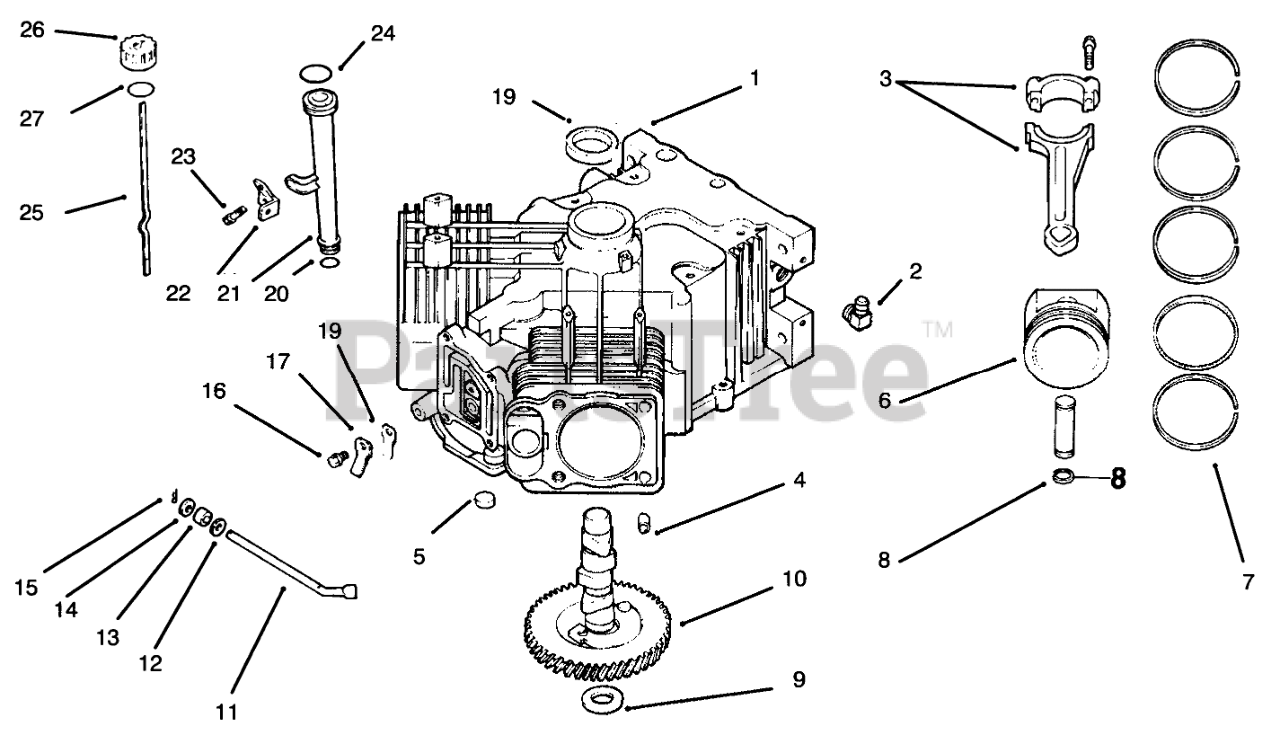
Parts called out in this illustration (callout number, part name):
1	Cylinder Block
2	Fitting
3	Rod-Connecting (Std)
4	Pin-Dowel
5	Plug-Cup
6	Set-Piston w/Ring (Incl. Ref. #7-8)
7	Set-Ring (Std)
8	Retainer-Piston Pin
9	Shim-Camshaft (Green)
10	Camshaft
11	Shaft-Governor Cross
12	Washer
13	Seal-Governor Cross
14	Washer
15	Pin-Hitch
16	Screw
17	Retainer-Reed
18	Beed-Breather
19	Seal-Oil
20	"O"Ring
21	Tube-Oil Fill
22	Bracket-Oil Fill Tube
24	"O"Ring
25	Dipstick Assembly (Incl. Ref. #26-27)
26	Kit-Fill Cap (Incl. Ref. #27)
27	"O"Ring
